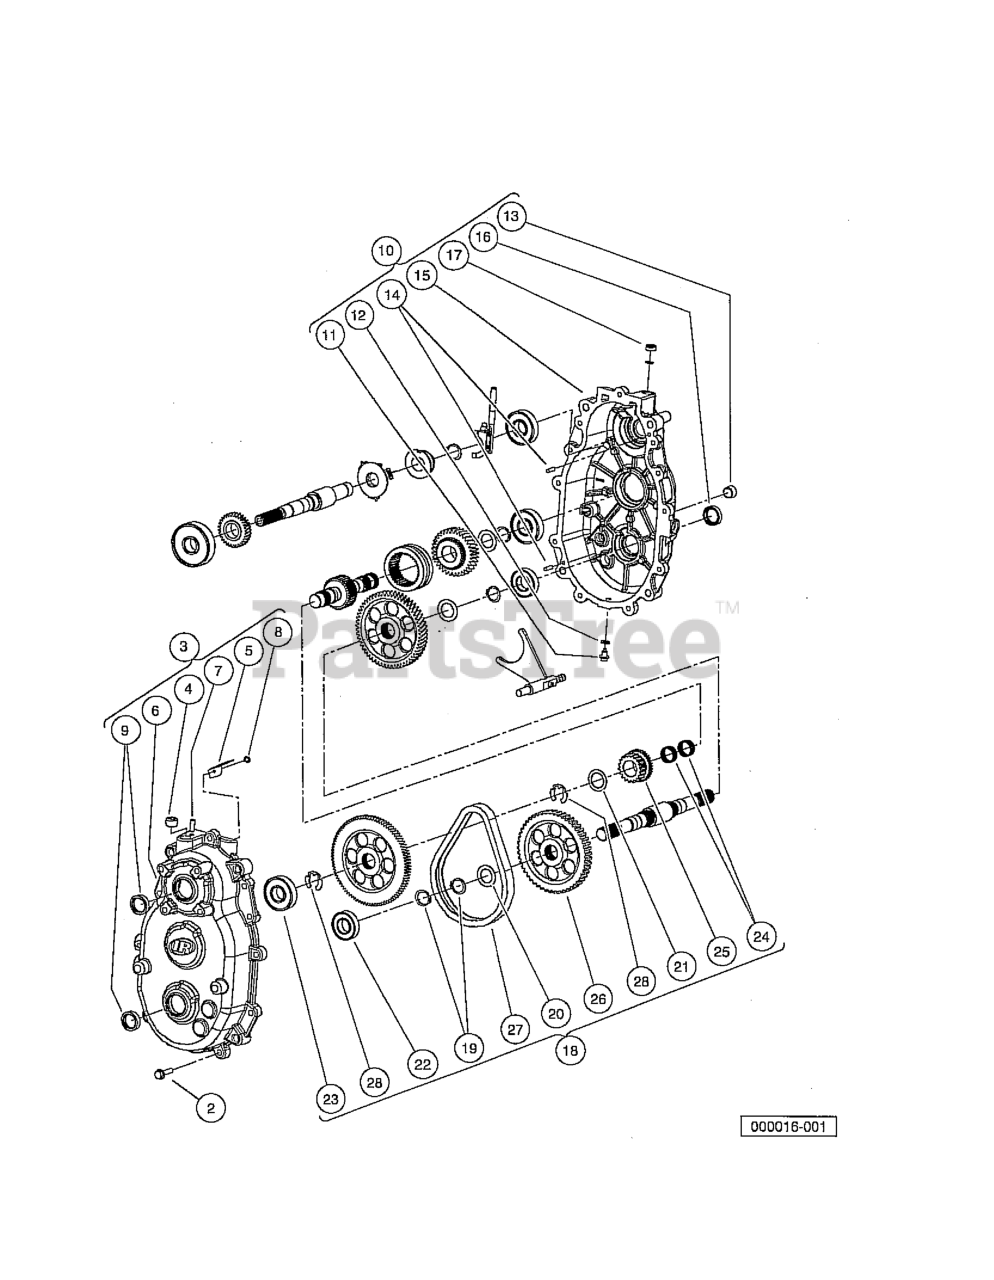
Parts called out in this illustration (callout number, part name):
2	SCREW, HEX FLANGE, M8 X 35
3	ASM-GEAR CASE REAR
4	PLUG, SQUARE SKIT, 1/12-14,PTF
5	OIL, DEFLECTOR
7	VENT, TRANS
8	SCREW, TAPPING #10-24 X .375
9	SEAL, TRIPLE, 25 X 35 X 7.8
10	ASM-GEAR CASE FRONT
11	PLUG,3/8-16, HEX FLANGE
12	WASHER, .625 X .382 X .60
13	PLUG, SQUARE SKIT, 1/12-14,PTF
14	PIN, DOWEL, 6 X 20
16	SEAL, TRIPLE, 25 X 35 X 7.8
17	SEAL, DUAL LIP
18	KIT-REVERSE GEAR REPAIR
19	RING, RETAINING, BASIC EXTERNA
20	WASHER, THRUST, 1.007 X .062
21	WASHER, 26.231 X 39.167 X 1.57
22	BEARING, BALL, 6205 C3
23	BEARING, BALL, 6305 C3
24	BEARING, NEEDLE, SPLIT CAGE
28	RING, RETAINING, E-RING, PO-10
